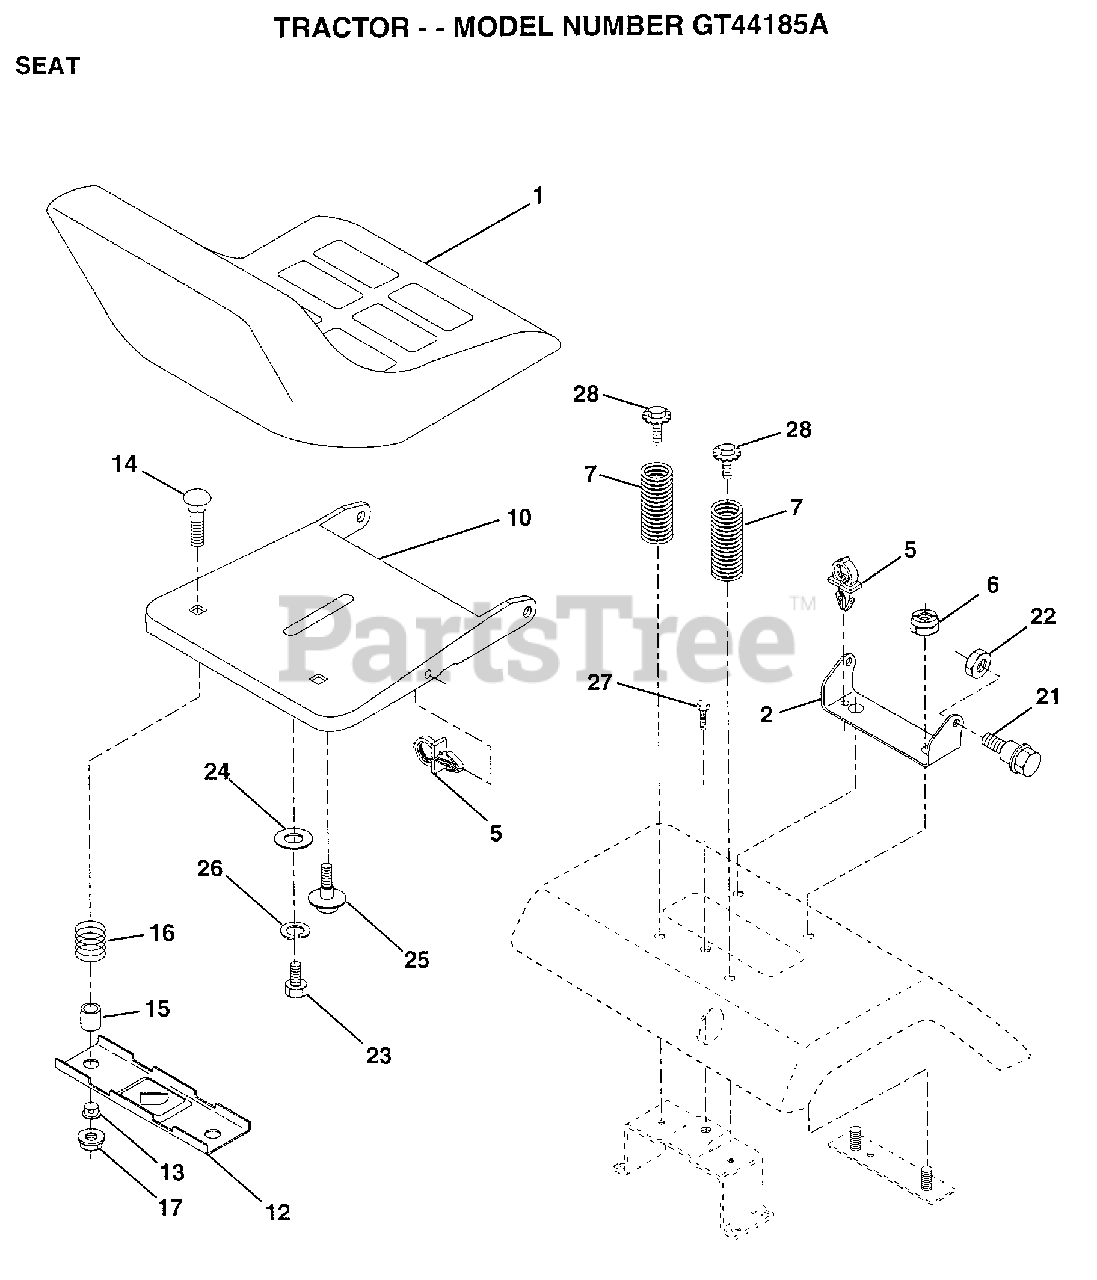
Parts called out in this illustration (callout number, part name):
1	SEAT.2500/1516.BK
2	BRACKET PVT SEAT
5	CLIP.PUSH-IN.HING
6	NUT
7	SPRING COMPRESSIO
12	BRKT SWITCH
13	BUSHING
15	SPACER SPLIT
16	SPRING COMPRESSED
21	"BOLT,SHOULDER"
23	BOLT
24	WASHER
25	"BOLT,SHOULDER"
26	LOCKWASHER
27	SCREW LT
28	BOLT.5/16-18.UNC
